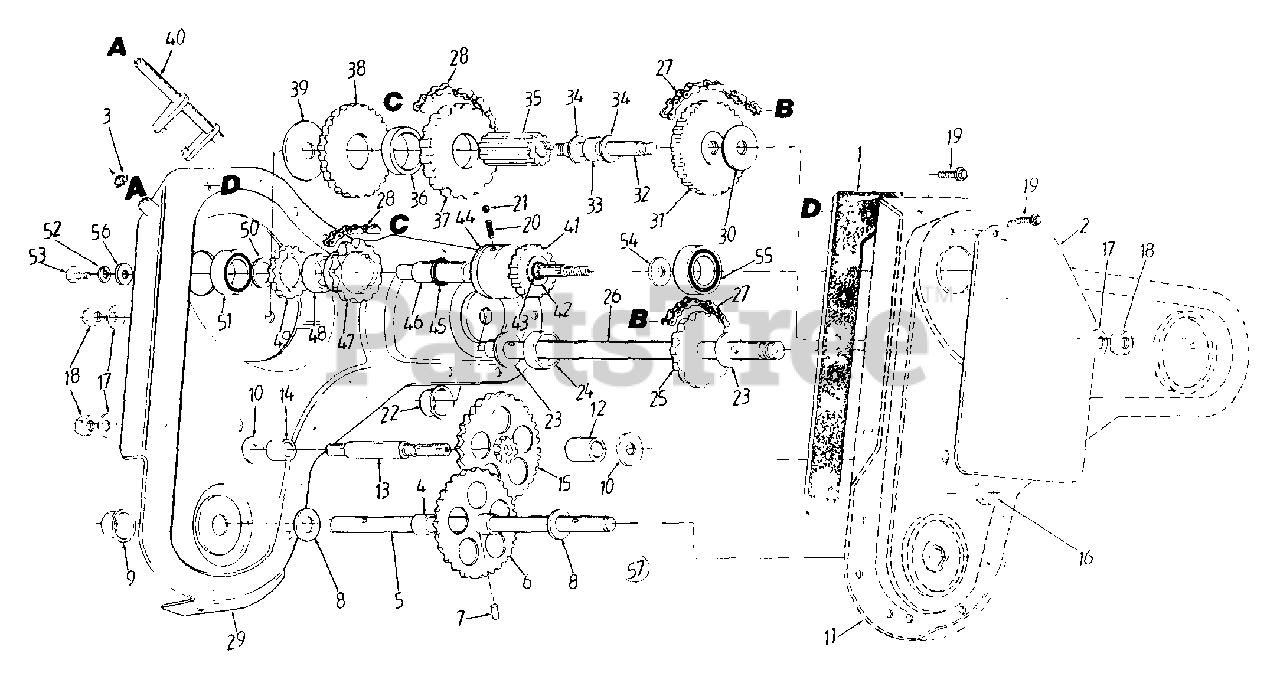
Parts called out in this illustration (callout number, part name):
1	Chain Case Gasket
4	Spacer .735" I.D. x .886" O.D.
5	Wheel Shaft
6	Spur Gear 46T
7	Pin Type "E" Grooved
8	Fl-Wash. .76" I.D. x 1.5" O.D.
9	Dust Cover Ass'y..75" Shaft
10	Fl-Wash. 7/16" I.D. x 1-3/8" O.D.
13	Jack Shaft 2.06" Lg.
14	Spacer .635" I.D. x 1" O.D. x .37" Thk.
15	Gear Idler Ass'y.
16	Hex Patch L-Nut 7/16-20 Thd.
17	Bell-Wash. .45" I.D. x 1" O.D.
18	Hex Nut 7/16-20 Thd.
19	Hex Wash. Hd. TT-Tap Scr. 1/4-20 x .5" Lg.
20	Spring Detent
22	Dust Cover Ass'y. 1" Shaft
23	Thrust Wash. 1.03" I.D. x 1.62" O.D.
24	Spacer 1" I.D. x 2" O.D. x .5" Thk.
25	18T Sprocket
26	Tine Shaft
27	Chain #50 5/8" Pitch x 52 Links - Endless
28	Chain - #41 1/2" Pitch x 30 Links - Endless
30	Fl-Wash 7/16" I.D. x 1-3/8" O.D.
31	Gear and Sprocket Ass'y.
32	Jack Shaft 5" Lg
33	Spacer .636" I.D x .86" O.D.
34	Fl-Wash .63" I D x .94" O.D.
35	Spur Gear 10T
36	Spacer 1.5" I.D. x 1.76" O.D.
37	Sprocket - #41 Chain
38	Reverse Gear 46T
39	Thrust Wash .445" I.D. x 1.92" O.D.
40	Shifter Ass'y.
41	Spur Gear 17T
42	Fl-Wash .69" I.D. x 1.06" O.D.
43	Retaining Ring .669" Shaft
44	Clutch Collar
45	Retaining Ring .875" Shaft
46	Drive Shaft
47	Sprocket 11T
48	Neutral Spacer
49	Spur Gear 16T
50	Fl-Wash 5/8" I.D. x 1" O.D.
51	Ball Bearing .669" I.D.
52	L-Wash 1/4" I.D.
53	Hex Bolt 1/4-20 x .62" Lg.
54	Fl-Wash .635" I.D. x 1" O.D.
55	Ball Bearing
56	Fl-Wash .281" I.D. x .875" O.D.
57	Gear Case Ass'y. Comp.
